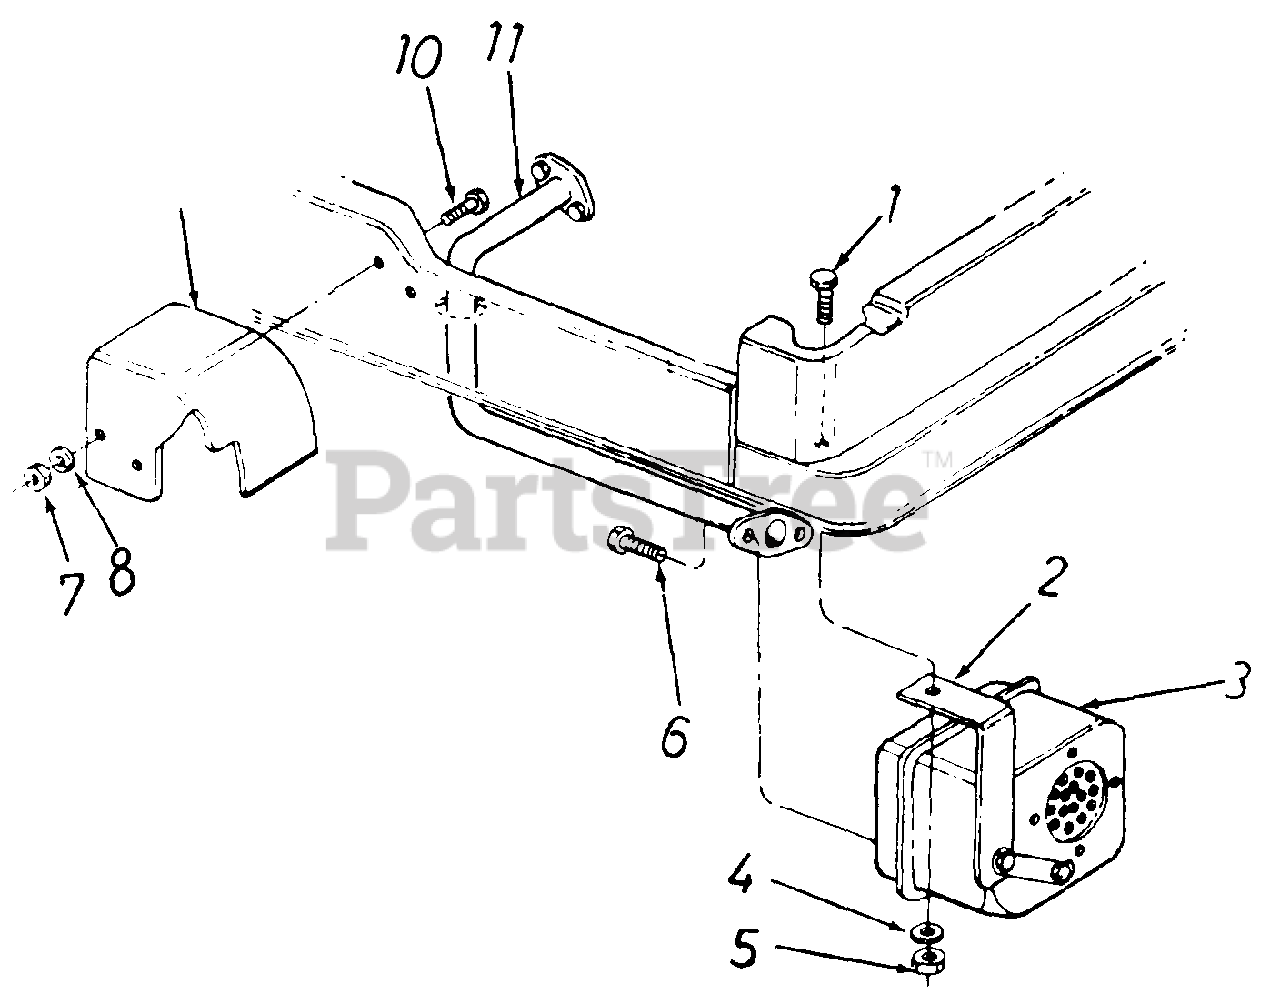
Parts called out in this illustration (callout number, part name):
1	Hex Scr. 1/4-20 x .50" Lg.
2	Muffler Strap
3	Muffler - Briggs & Stratton
4	L-Wash. 1/4 I.D.
5	Hex Nut 1/4-20 Thd.
6	Hex Scr. 1/4-20 x .50" Lg.
7	Hex Nut 1/4-20 Thd.
8	L-Wash. 1/4 I.D.
10	Hex Scr. 1/4-20 x .50" Lg.
11	Exhaust Pipe Ass'y.
